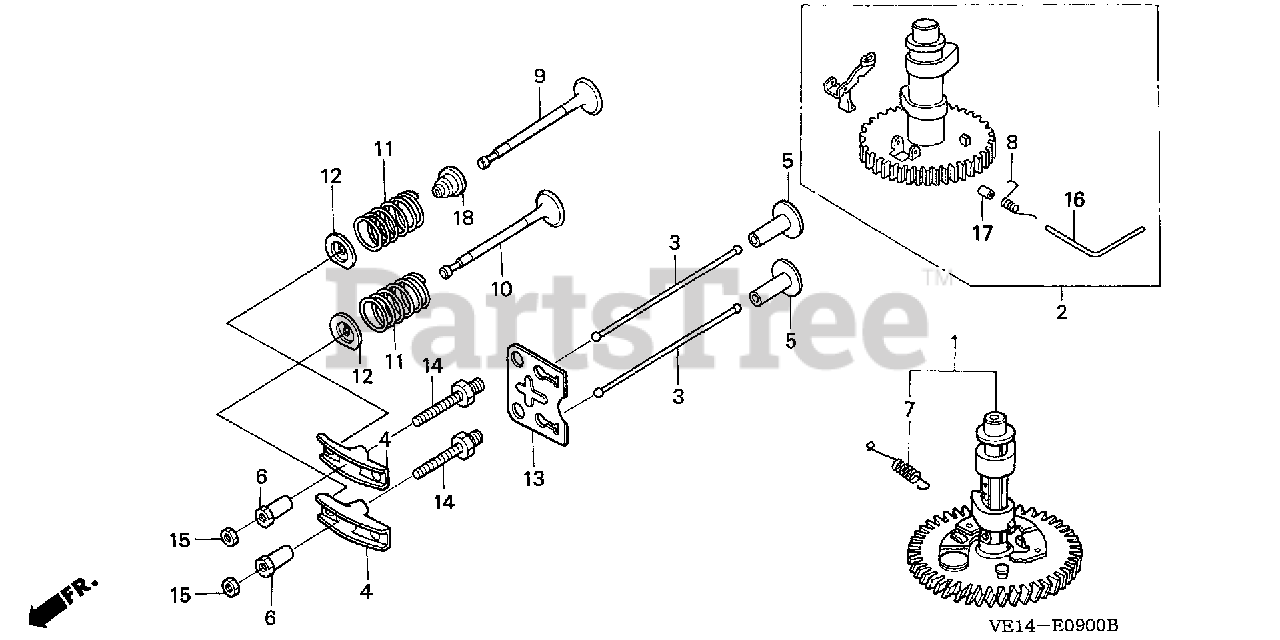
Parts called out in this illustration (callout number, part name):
2	CAMSHAFT ASSY.
4	ARM, VALVE ROCKER
5	LIFTER, VALVE
6	PIVOT, ROCKER ARM
8	SPRING, WEIGHT RETURN
9	VALVE, IN.
10	VALVE, EX.
11	SPRING, VALVE
12	RETAINER, IN. VALVE SPRING
13	PLATE, PUSH ROD GUIDE
14	BOLT, PIVOT (8MM)
15	NUT, PIVOT ADJUSTING
16	PIN, WEIGHT CENTER
17	COLLAR, WEIGHT CENTER
